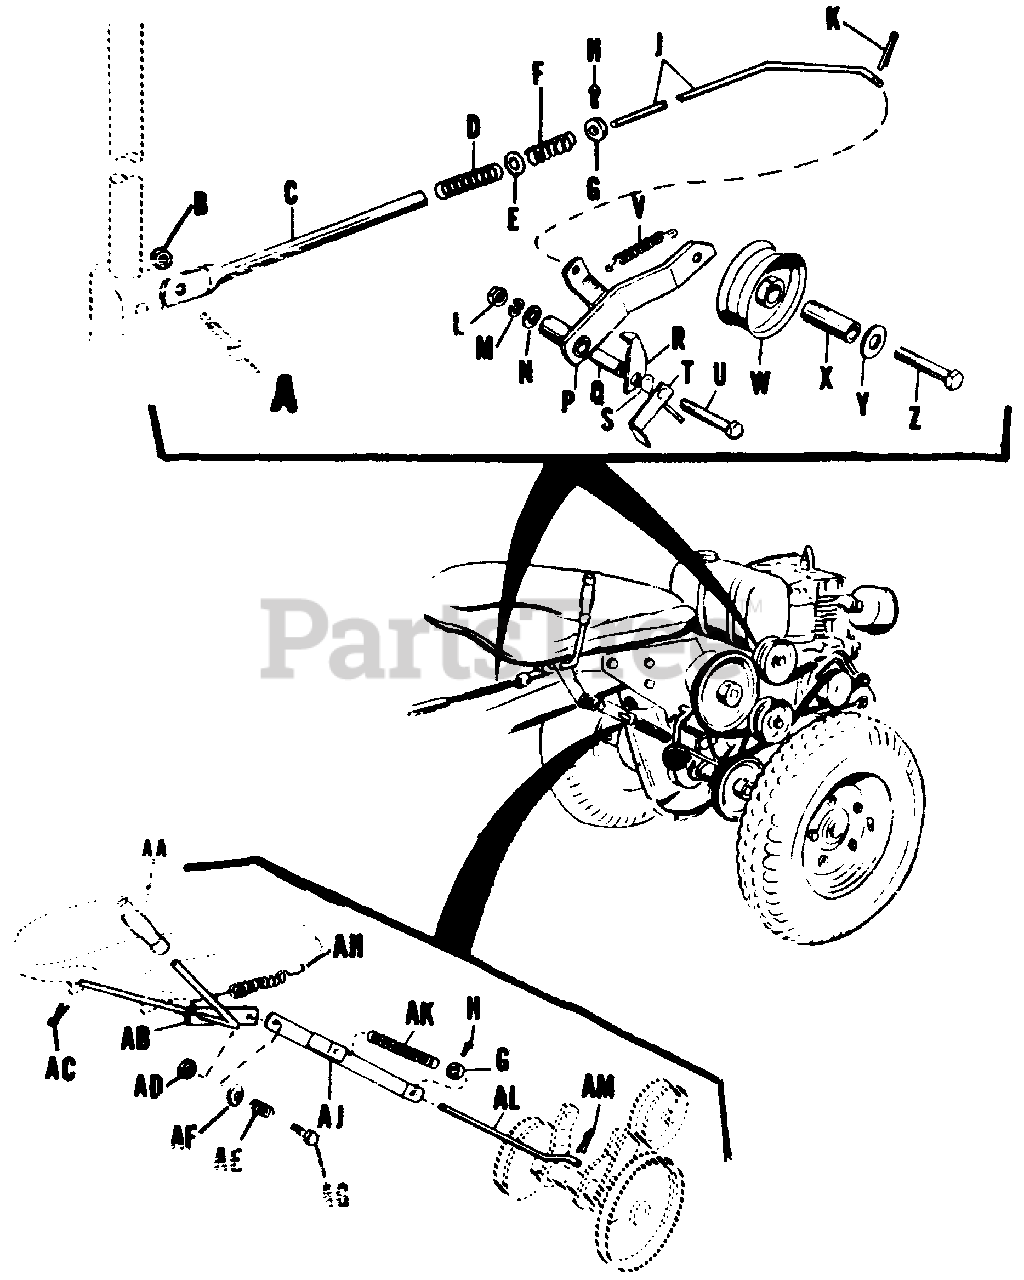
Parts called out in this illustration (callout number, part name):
A	Capscrew, Hex Hd., 5/16-18 x 3/4
B	Nut, Lock, Full Hex, 5/16-18
C	Rod, Front Clutch Assembly
E	Washer, Plated, 5/16
G	Collar, Set
H	Set Screw, Sq. Hd., 1/4-20 x 3/8
J	Rod, Rear Clutch
K	Pin, Cotter, 3/32 x 5/8
L	Nut, Full Hex, 3/8-16
M	Washer, Lock, 3/8
N	Washer, Plain, 3/8
P	Lever Assembly, Idler
R	Step, Lever
S	Pin, Lock
T	Guide, Belt
U	Capscrew, Hex Hd., 3/8-16 x 1 1/4
W	Pulley, Idler
X	Race, Inner Bearing
Y	Washer, Plain, 3/8
Z	Capscrew, Hex Hd., 3/8-6 x 2
AB	Lever Assembly
AC	Pin, Cotter, 1/8 x 1
AD	Nut, Lock, Full Hex, 3/8-16
AF	Washer, Plain, 5/16
AG	Capscrew, Hex Hd., 3/8-16 x 1 1/4
AJ	Guide Assembly
AL	Rod, Clutch
AM	Pin, Cotter, 3/32 x 5/8
